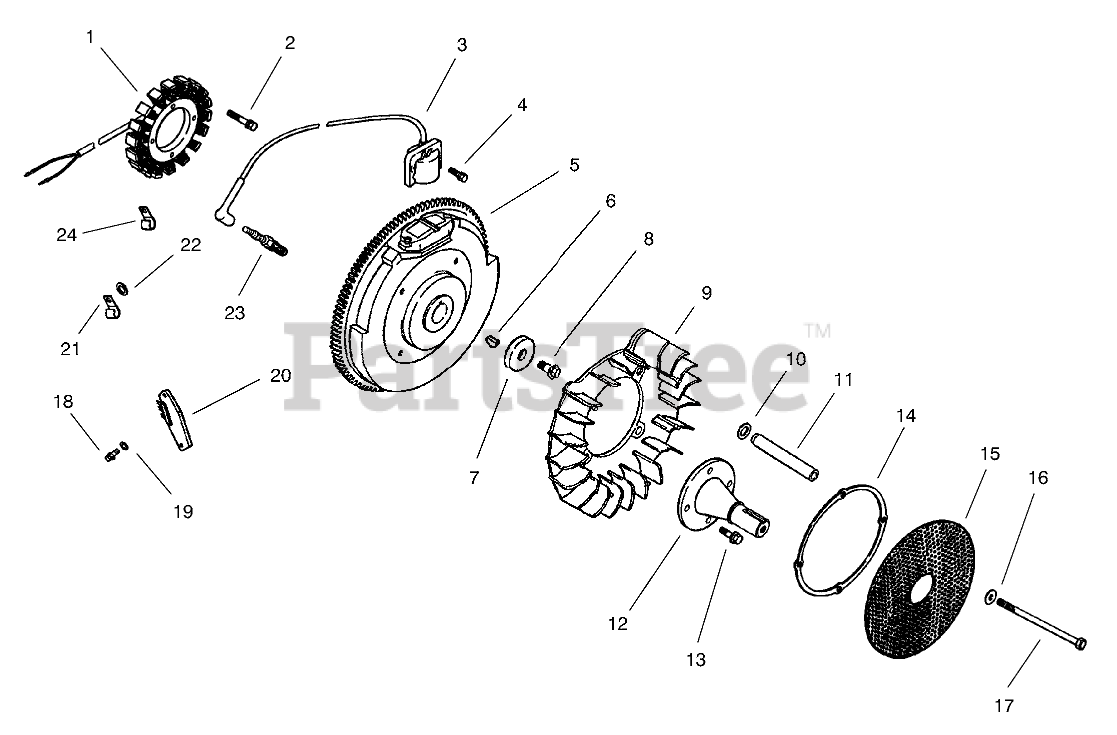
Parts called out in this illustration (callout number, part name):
1	Kit, 15 amp stator (Incl. 24 126 71 bracket)
2	Screw
3	Module-Ignition
4	Screw
5	Flywheel
6	Key
7	Washer
8	Screw
9	Fan
10	Washer, sping
11	Spacer
12	Shaft, front drive
13	Screw
14	Ring-Support
15	Screen-Grass
16	Washer
17	Screw-Hex
18	Screw
19	Washer
20	Rectifier-Regulator
21	Clip
22	Washer
23	Plug-Spark
24	Clip
